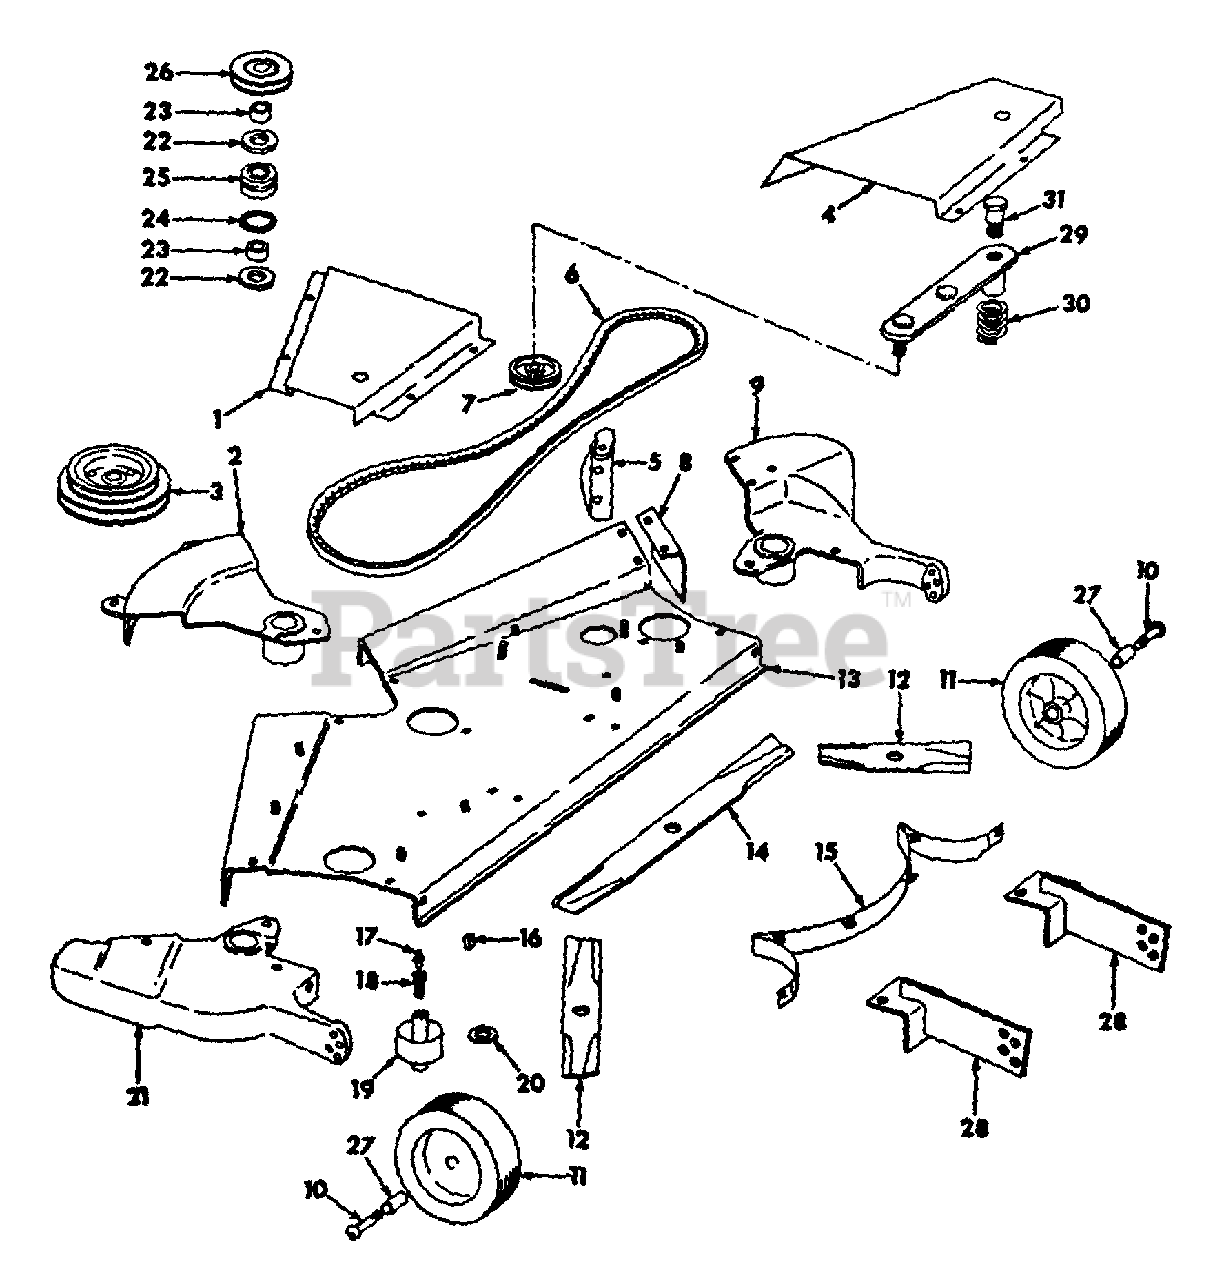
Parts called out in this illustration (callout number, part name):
1	SHIELD, BELT LH
2	CENTER, ROTOR HOUSING
3	PULLEY, CENTER
4	SHIELD, BELT RH
5	RUNNER HOUSING RH
6	BELT, SPINDLE DRIVE
7	PULLEY, FLAT IDLER
8	MULCHER PARTS ACCESSORY
9	END, ROTOR HOUSING RIGHT
10	BOLT, SHOULDER
11	WHEEL, 7 IN. GAUGE
12	BLADE, OUTER
13	HOUSING ASSY, ROTOR
14	BLADE, CENTER
15	SHROUD ASSY, BLADE
16	KEY, 1/4 x 3/4 x SQ. PARALLEL
17	FITTING, 3/16 STR DRIVE LUB
18	BOLT, END
19	DISC AND SPINDLE ASSY, BLADE DRIVE
20	WASHER, BLADE FRICTION
21	END, ROTOR HOUSING LEFT
22	SEAL, SPINDLE OIL
23	SPACER, PULLEY
24	SPACER, SPLIT OUTER
25	BEARING ASSY, SPINDLE
26	PULLEY, OUTER
27	BUSHING, WHEEL
28	SUPPORT ASSY, GAUGE WHEEL
29	ARM ASSY, IDLER
30	SPRING, TORSION
31	BOLT, IDLER ARM PIVOT
18655-R1	BOLT, 1/4-20 x 1 C-Z HEX-HD MACH
18684-R1	BOLT, 3/8-16 x 1-1/4 C-Z SQ-NK CRG
18685-R1	BOLT, 3/8-16 x 1-1/2 C-Z SQ-NK CRG
19417-R1	BOLT, 3/8-16 x 1 C-Z SQ-NK CRG
180123	SCREW, 3/8-16 x 1-1/8 C-Z HEX-HD CAP
